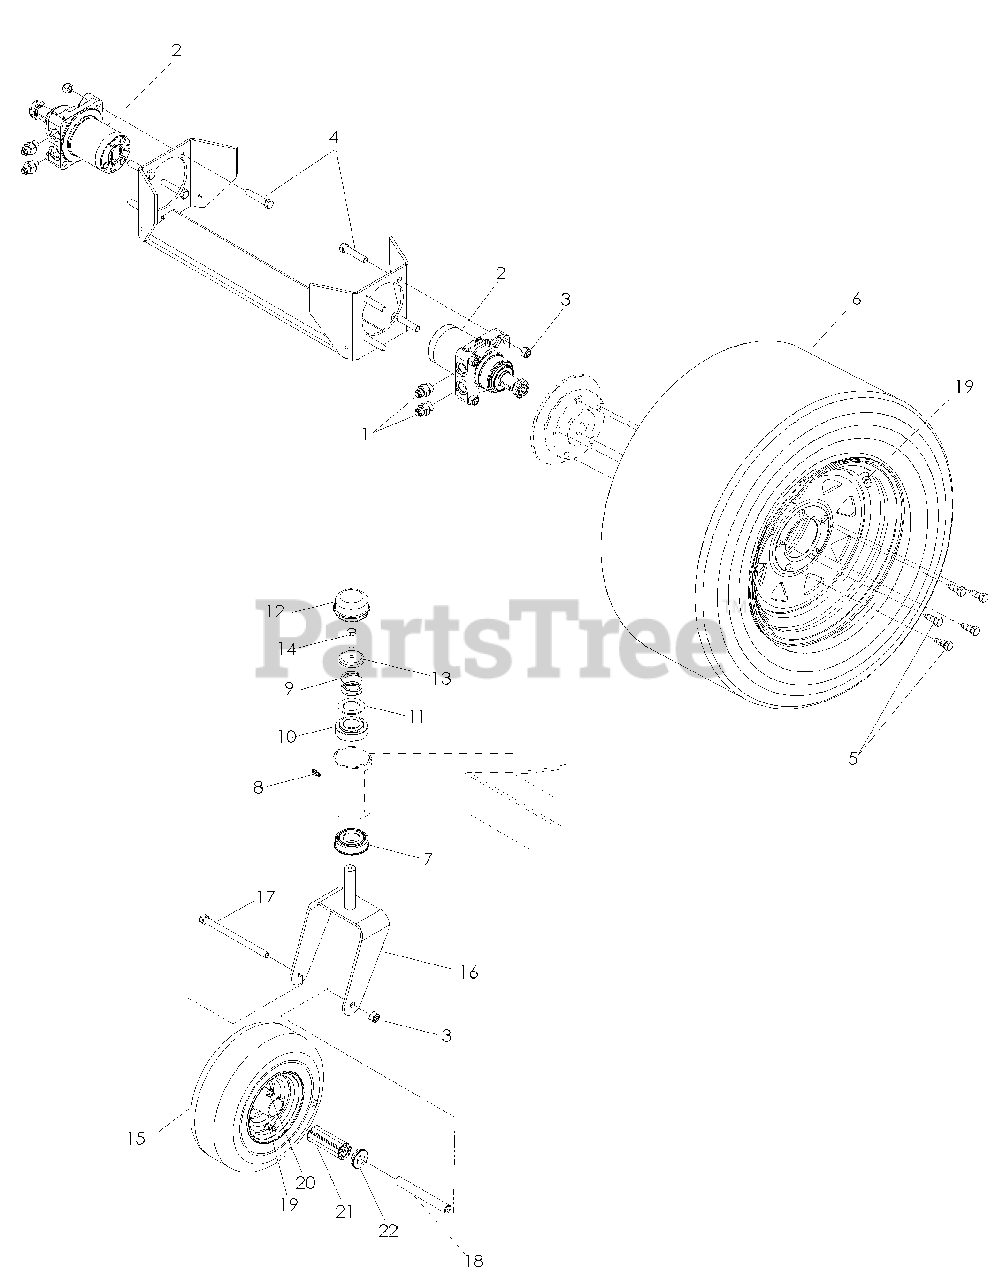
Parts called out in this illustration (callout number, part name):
1	CONNECTOR, STRAIGHT
2	WHEEL MOTOR, TJ
3	NUT 1/2-13 HEX NYLOC ZD
4	HEX SCREW 1/2-13 X 2.5" GR 5
5	HUB BOLT
6	WHEEL.R.TS.23X10.5-12.C.MS
7	BEARING FLANGED
8	ZERK, 3/16, DRIVE IN
9	SPRING, CASTER
10	BUSHING, CASTER
11	WASHER, 1.025 ID X 1.64
12	GREASE CAP
13	CASTER.PLUG
14	HCS 5/16C X 1
15	TIRE.ASSEM.13X5-6.SMOOTH.SILVE
16	YOKE, CASTER - BLUE
17	SCREW 1/2C X 7 1/2 HEX CAP
18	SPACER, CASTER
19	VALVE STEM TR-412
20	ZERK 1/8 NPT
21	ROLLER BEARING
22	BEARING RETAINER
